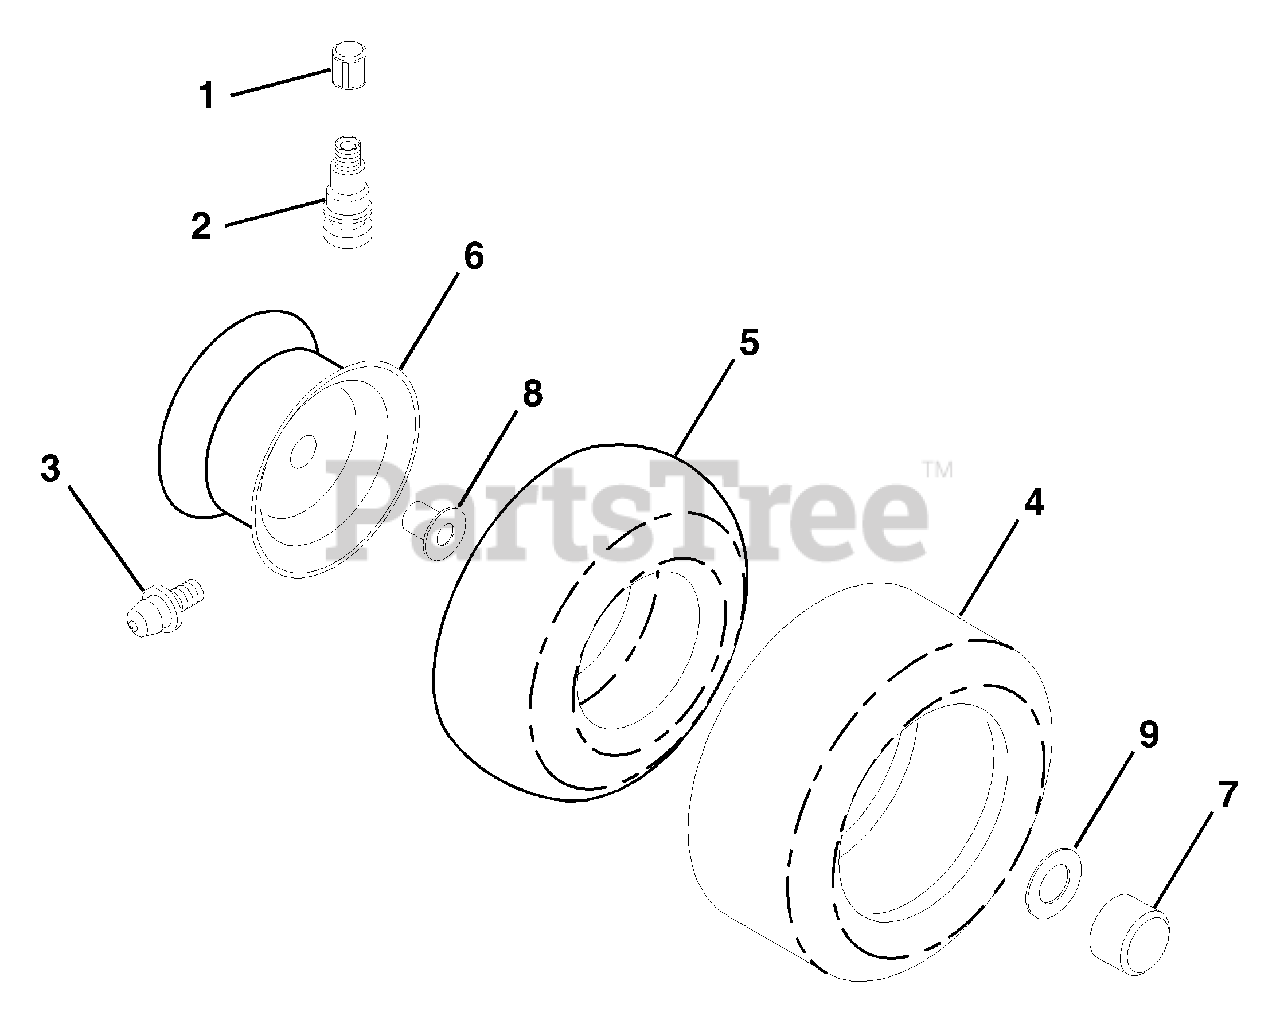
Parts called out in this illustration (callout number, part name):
1	Cap, Valve
2	Stem, Valve
3	Fitting, Grease (Front Wheels Only)
4	Tire, Front
4	Tire, Rear
5	Tube, Front
5	Tube, Rear
6	Rim, Front
8	Bearing Flange
9	Washer 25/32 x 1-5/8 x 16 Ga.
